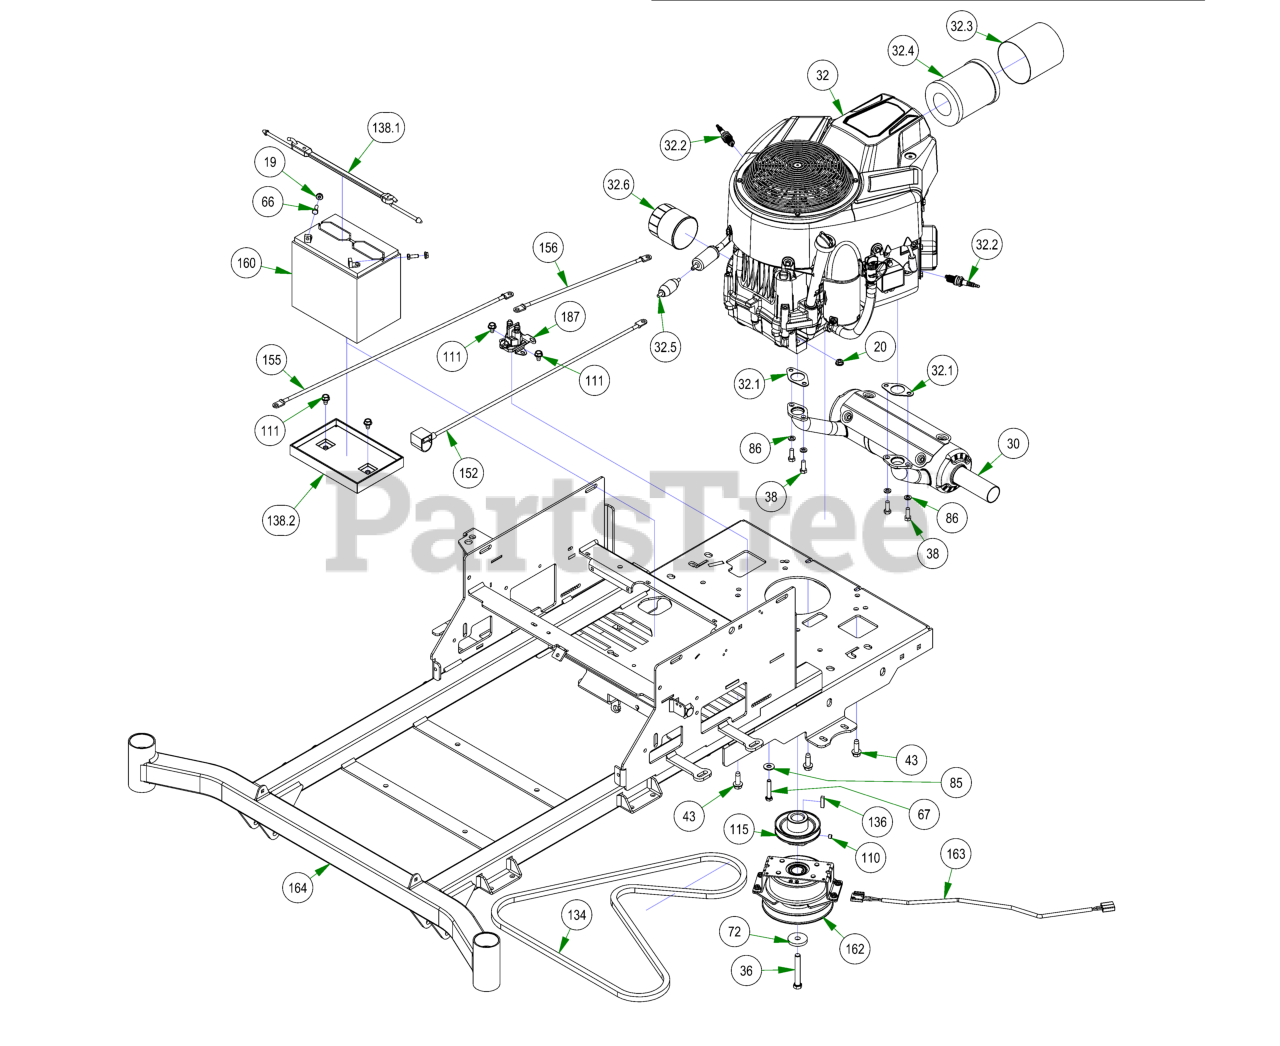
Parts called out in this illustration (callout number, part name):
19	1/4-20 HEX SERRATED FLANGE NUT HARD/ZINC
20	5/16-18 HEX SERRATED FLANGE NUT HARD/ZINC
30	2017 Compact Outlaw Exhaust 810 Vanguard
32	Vanguard 25hp CXI with out Oil Filter 1" Shaft ZT Avenger
32.1	Exhaust Gasket
32.2	Spark Plug
32.3	pre-Cleaner for Vanguard CXI Engine
32.4	Air Filter for Vanguard CXI Engine
32.5	Universal Inline Fuel Filter
32.6	Oil Filter
36	7/16-20x3” Hex Bolt GR 8 W/ Patch
38	Torx Bolt-Exhaust
43	3/8-16 X 1-1/8HEX WASHER UNSLOT SERRATED (TRI-LOB) TRS
66	1/4-20 X 3/4 HEX CAP SCREW (GR.5) ZINC
67	5/16-18 X 1-3/4 HEX CAP SCREW (GR.5) ZINC
72	CLUTCH WASHER
85	5/16 USS FLAT WASHER (7/8 OD) ZINC
86	5/16 SPLIT LOCKWASHER ZINC
110	5/16-24 X 1/4 SOCKET SET SCREW (CUP PT) PLAIN
111	5/16-18 X 1/2 HWH unslot (F) tcs zinc
115	3-3/4" Motor Pulley
136	1/4 X 1 SQ MACHINERY KEY 1018 STL PLN
138	2023 Battery Hold Down Assembly Strap
138.1	2023 Rubber Battery Hold Down Strap
138.2	Battery Tray
152	24 inch Black Cable – MZ/ZT
155	24" Red Battery Cable
156	12 in red battery cable
160	SP-35 Battery
163	Clutch Pigtail
164	2023 MZ-Avenger 54-60 Frame - Painted
